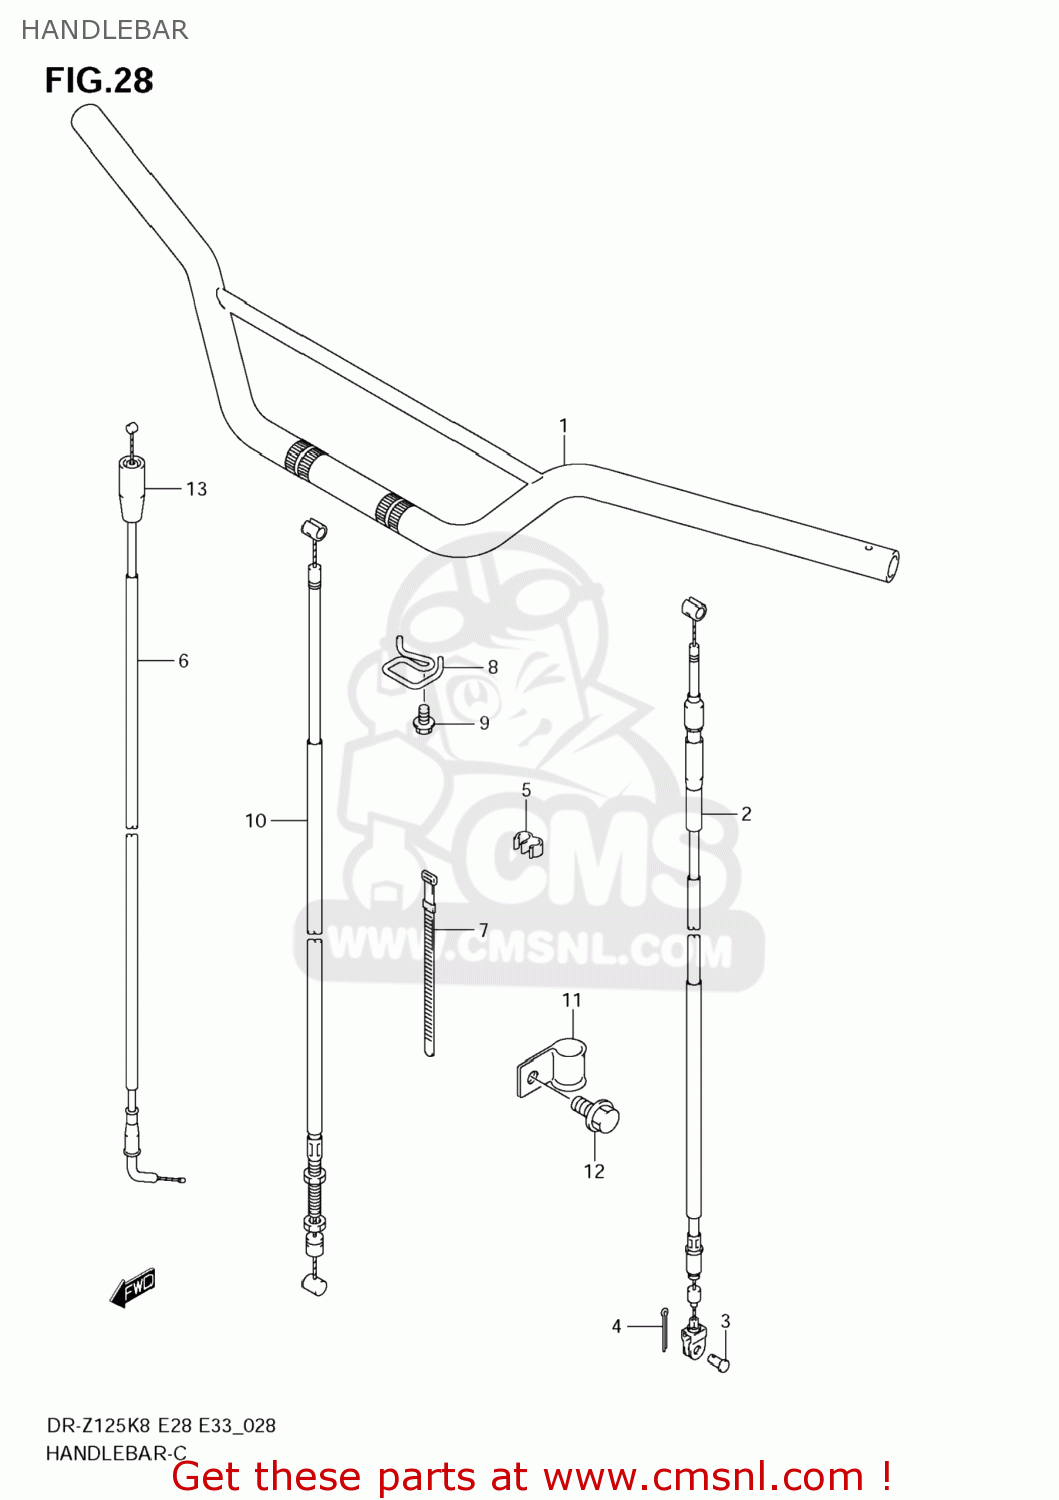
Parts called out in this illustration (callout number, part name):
1	HANDLEBAR(SILVER)
2	CABLE ASSY,CLUTCH
3	PIN(L:13)
4	PIN
5	CLAMP
6	CABLE ASSY,THROTTLE
7	CLAMP(L:90)
8	GUIDE,CABLE
9	BOLT
10	CABLE,FR BRAKE
11	CLAMP,FR BRAKE CABLE
12	BOLT
13	COVER,THROTTLE CASE
